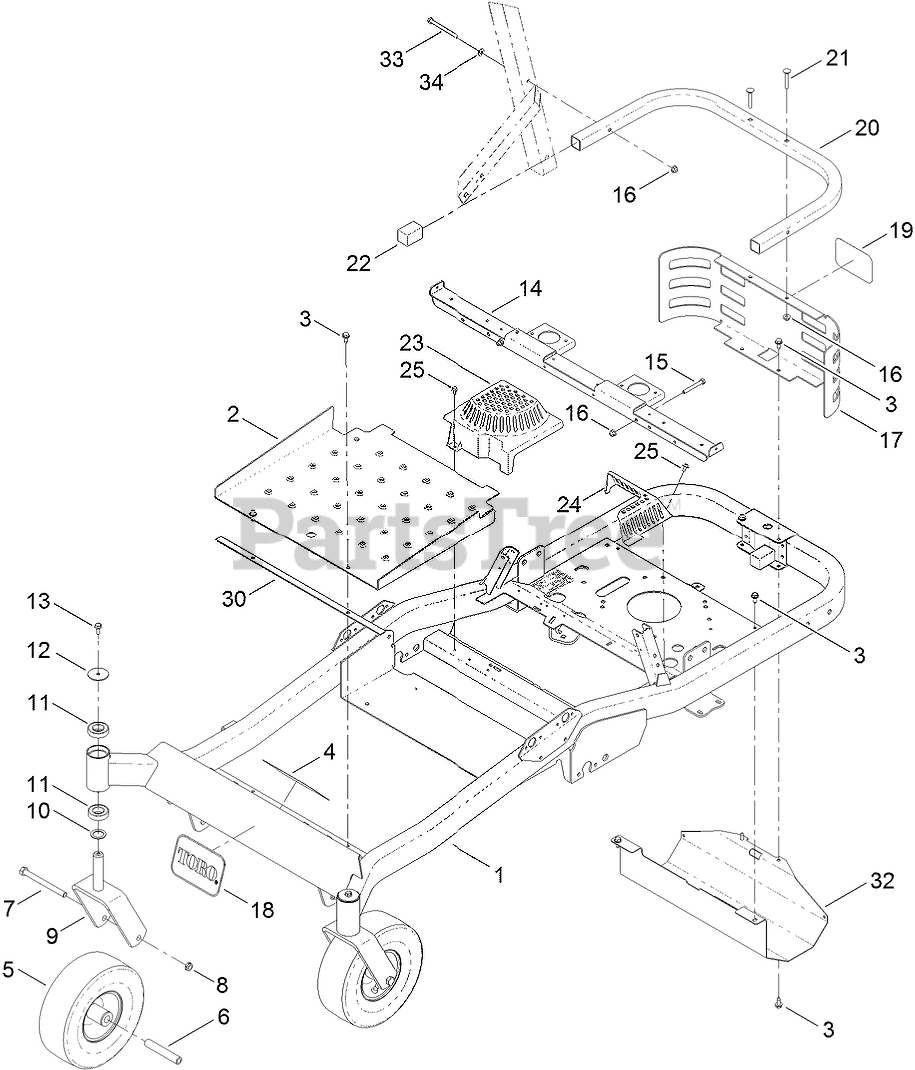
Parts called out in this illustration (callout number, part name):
2	PAN-FLOOR
3	SCREW-HWHTF
4	DECAL-SAFETY
5	WHEEL AND TIRE ASM
6	SPACER-SPANNER
7	SCREW-HH
8	NUT-LOCK, NI
9	FORK-CASTER
10	WASHER-THRUST
11	BEARING-BALL
12	WASHER
13	SCREW-HHF
14	SUPPORT-SEAT
15	SCREW-HH
16	NUT-HF, NI
17	GUARD-REAR
18	DECAL
20	TUBE-GUARD
21	Screw-CARR
23	COVER-FAN, RH
24	COVER-FAN, LH
25	SCREW-HHFTF
30	STRIP-VIBRATION, ANTI
32	GUARD-MUFFLER
33	SCREW-HH
34	WASHER-PLAIN
